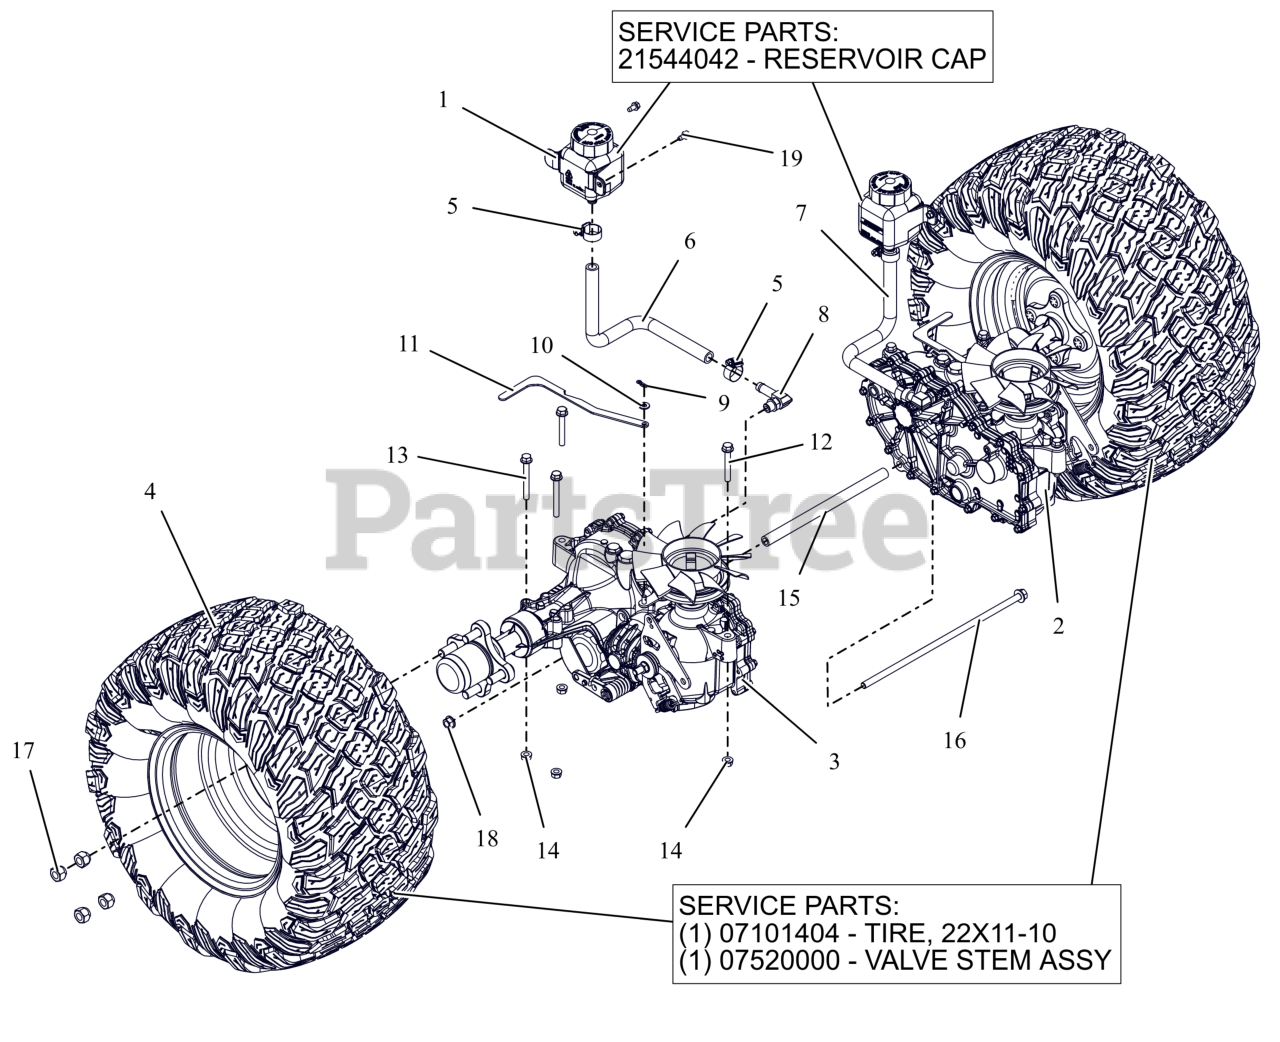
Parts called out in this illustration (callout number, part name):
1	TANK, EXPANSION
1	CAP, HYDRO RESERVOIR REPLAC.
2	TRANSAXLE, ZT3100 - LH
3	TRANSAXLE, ZT3100 - RH
4	ASM- TIRE/WHL 22X11-10
4	TIRE- 22X11-10 K3012
4	VALVE STEM ASS'Y
5	CLAMP,.88 DIA. HOSE
6	HOSE, FORMED EXPANSION -HD RH
7	HOSE, FORMED EXPANSION -HD LH
8	FITTING, HYD (90 DEG)
9	PIN, HAIR #225 .072X1.09
10	WSHR,FLT .281X.625X.065 ZCC
11	BRKT, VALVE DUM
12	BLT,HEX-FLG .31-18X2.25 G5 ZCC
13	BLT,HEX-FLG .31-18X2.75 G5 ZCC
14	NUT,LK-CTR-FLG .31-18 GF ZCC
15	SPCR, TRANSAXLE .406 ID X .630 OD X 9.95LG (BLACK)
16	BLT, HEX-FLG 0.375-16X13 GR5 ZC120
17	NUT, WHEEL .50-20 ZCC
18	NUT-LK-TOP-FLG .38-16 ZC120
19	SCR-TAP .25-20X.50 HWH ZCC
